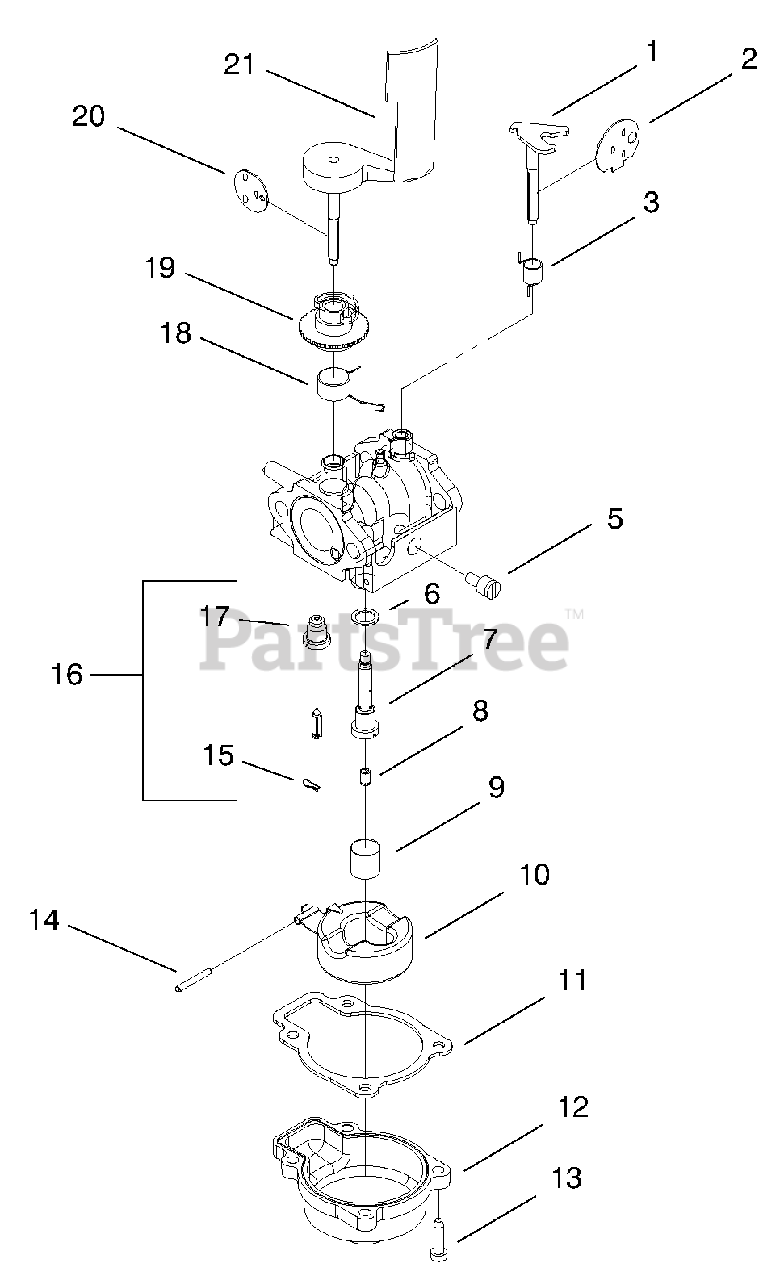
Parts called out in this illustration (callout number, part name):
1	Shaft-Choke
2	Disc-Choke
3	Spring-Choke Return
5	Pilot-Jet
8	Mainjet 77.5
9	Filter-Fuel
10	Float & Arm ASM
11	Gasket-Float Chamber
12	Float Chamber
15	Clip
16	Float & Valve ASM
17	ASM-Seat
18	Spring-Throttle
19	Collar Adjustment
20	Disc-Throttle
21	Air Vane & Shaft
